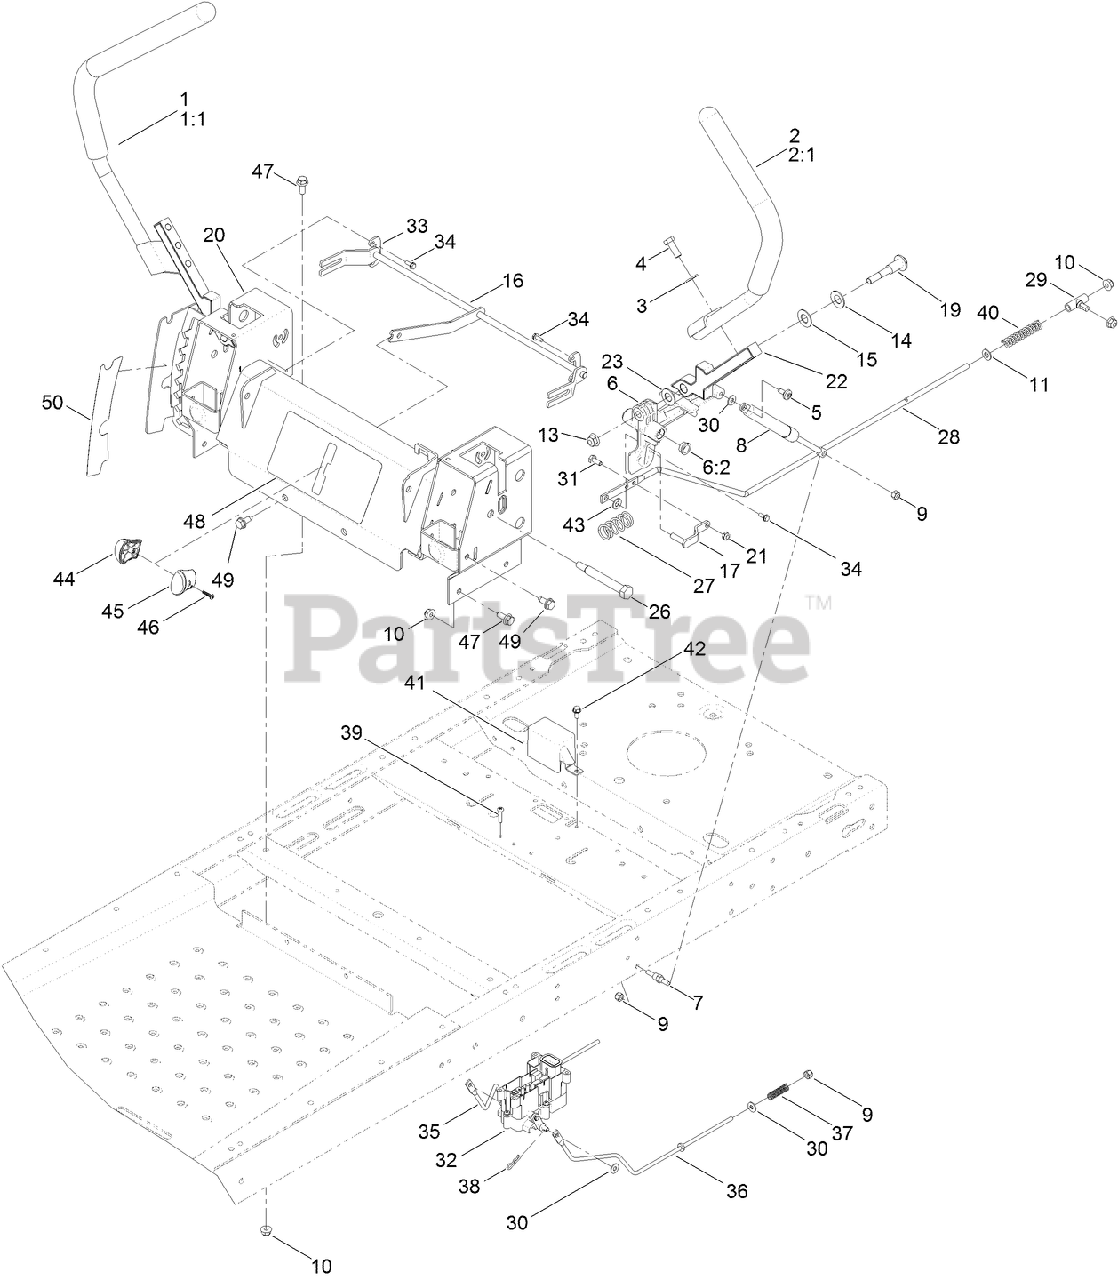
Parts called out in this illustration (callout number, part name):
1	HANDLE-CONTROL, RH
2	HANDLE-CONTROL, LH
3	WASHER-FLAT
4	SCREW-HH
5	SCREW-SHOULDER
6	ACTUATOR ARM ASM
6:2	BUSHING-FLANGE
7	STUD-DAMPER
9	NUT-LOCK, NI
10	NUT-HF, NI
11	WASHER-PLAIN
13	NUT-HF, NI
14	WASHER-BELLEVILLE
15	WASHER
16	CONTROL-SPEED
19	BOLT-PIVOT
20	CONTROL BOX ASM
21	NUT-LOCK, NI
23	WASHER-NYLON
26	BOLT-PIVOT
27	SPRING-RETURN
28	ROD-HYDRO
29	MOUNT-ROD, HYDRO
30	WASHER
31	SCREW-HH
32	BRAKE CONTROL MODULE ASM
33	RETAINER
34	SCREW-TAPTITE
35	ROD-BRAKE, RH
36	ROD-BRAKE, LH
37	SPRING-COMPRESSION
39	SCREW-PPH
40	SPRING-RETURN, NEUTRAL
41	COVER-BRAKE
42	SCREW-HWH
43	SPACER-NYLON
46	SCREW-PPH
47	SCREW-HHF
48	DECAL-SPEED CONTROL
49	SCREW-HWHTF
50	DECAL-HOC, CE
